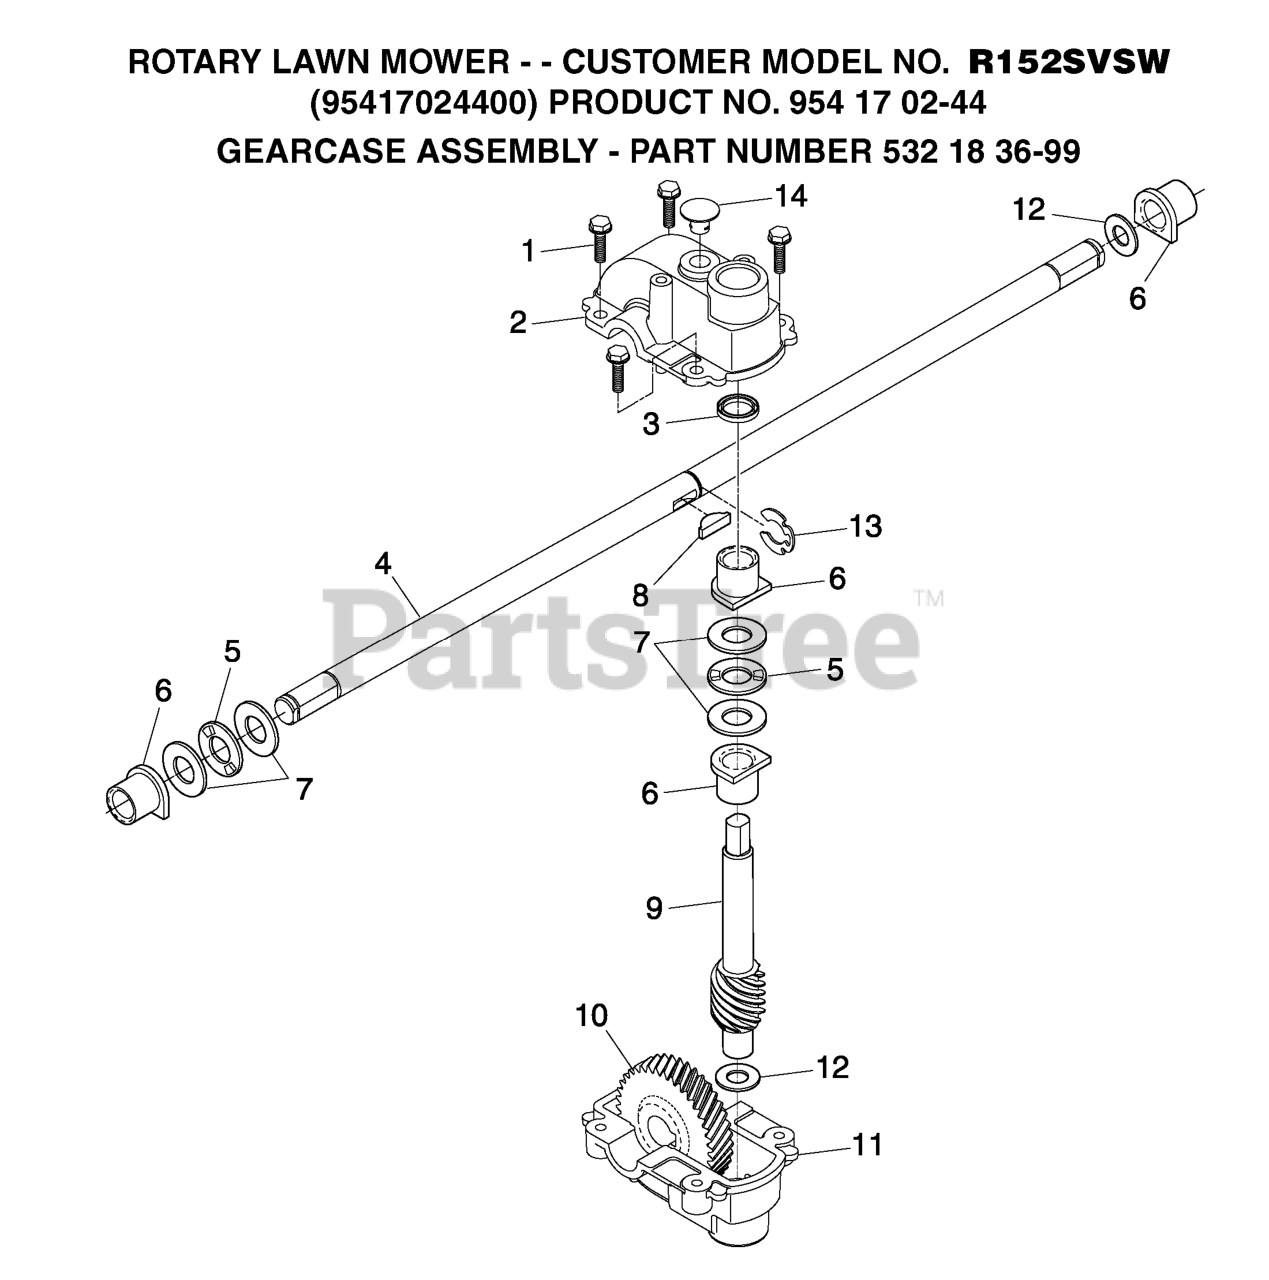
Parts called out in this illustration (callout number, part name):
1	Screw, Hex Washer Head #10-24 x .668
2	GEAR CASE, UPPER
4	SHAFT.DRIVE.HI-VAC.EZ
5	BEARING, NEEDLE, THRUST
7	WASHER, THRUST
8	HI PRO KEY
9	SHAFT.WORM.HI-VAC
10	GEAR, HELICAL
11	GEAR CASE, LOWER
12	THRUST WASHER
14	PLUG.AUGER.GEAR.BOX.SNOW
